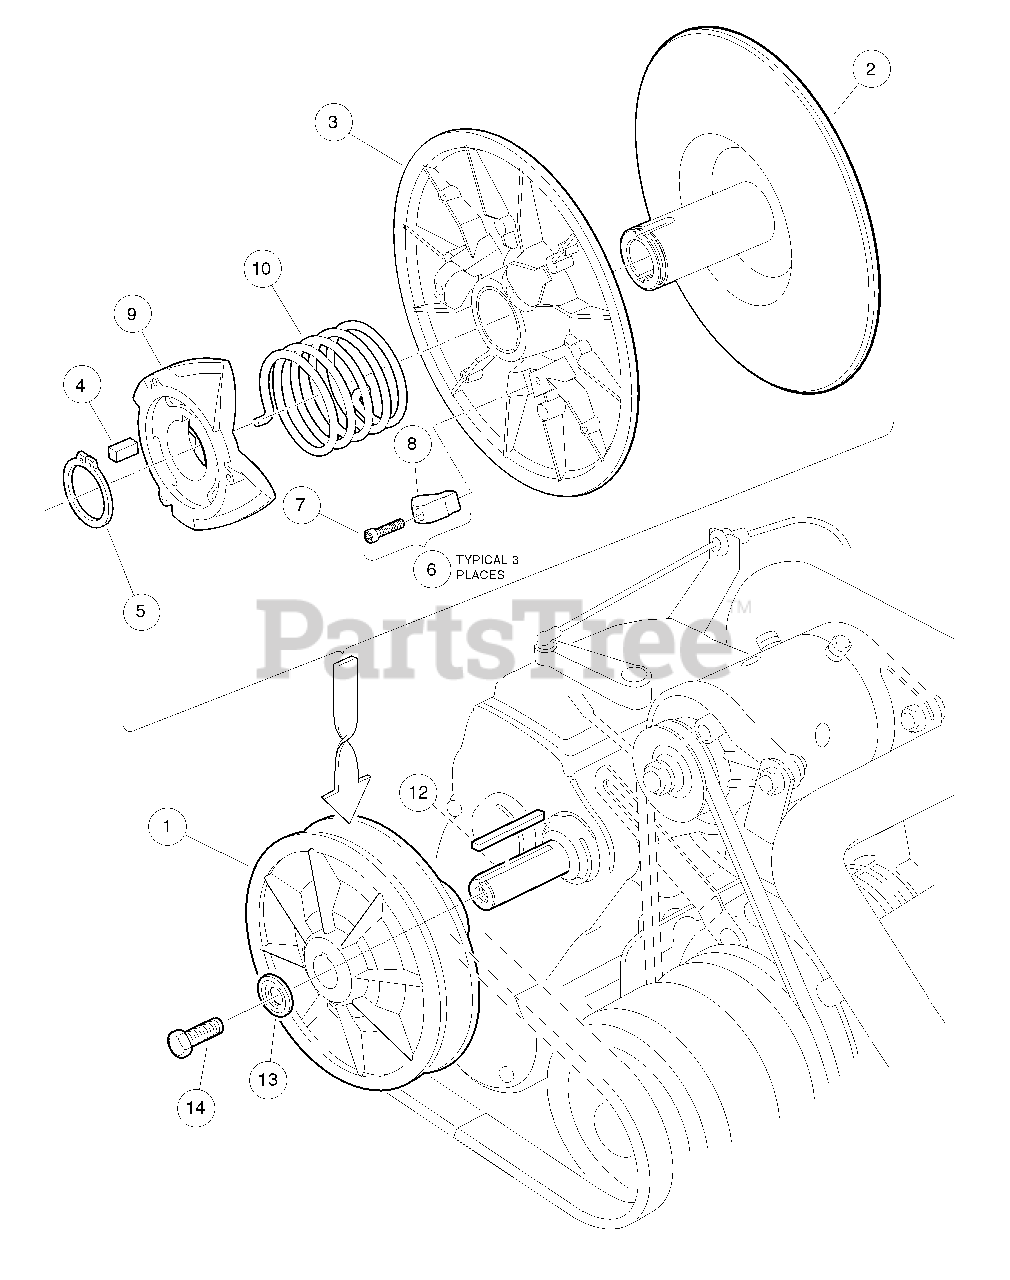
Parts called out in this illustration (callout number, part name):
1	Assembly, Driven Clutch
2	Fixed Face Assy, Driven Clutch
3	Movable-Face Assembly with Bushing
4	Key, Driven Clutch
5	Ring, Retaining
6	Kit, Driven Clutch Button
7	Screw, #8-32 X 3/4 Socket-Head Cap
8	Button, Drive
9	Cam, Driven Clutch
10	Spring, Driven Clutch, Reversed
11	Kit, Clutch Repair
12	Key, 3/16 Sq X 1.50"
13	Washer, Driven Clutch
14	Screw, 5/16-18 X 3/4 Hex-Head with Patch
